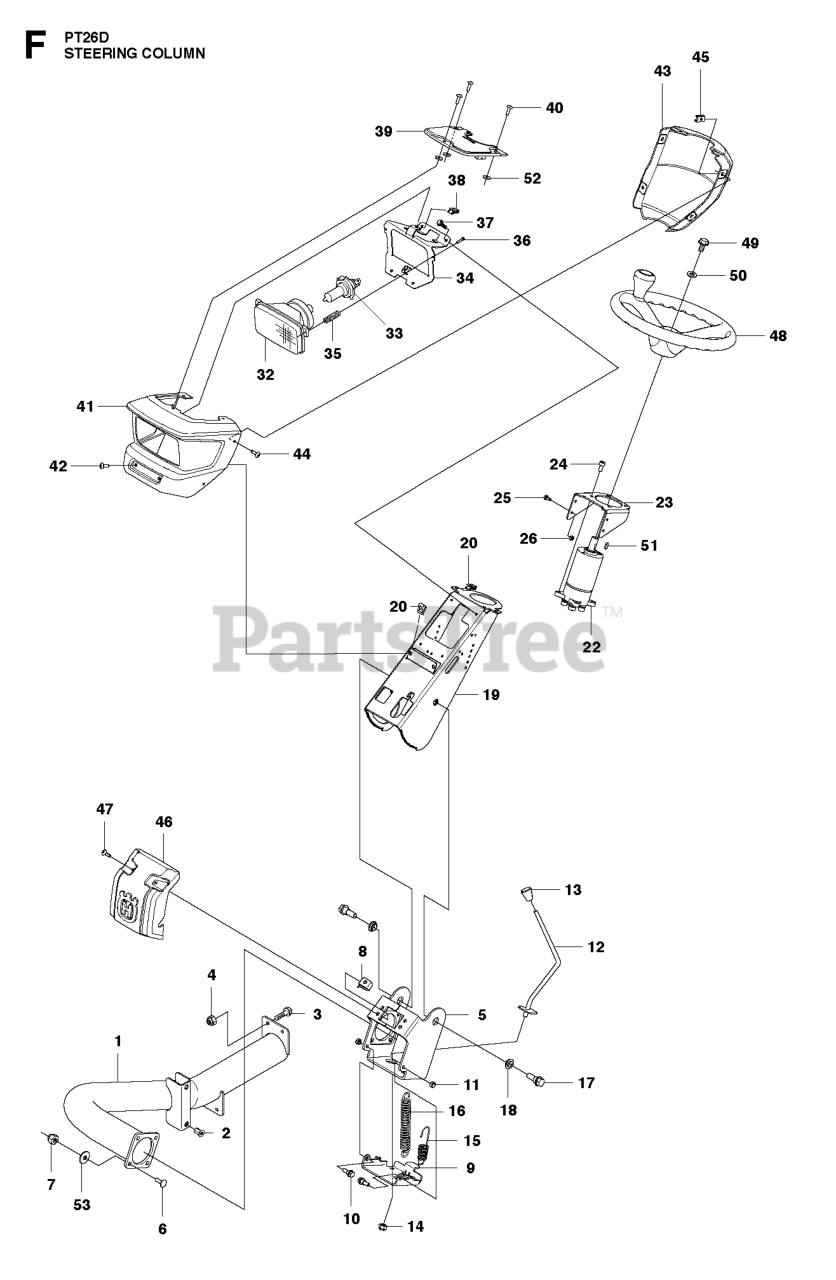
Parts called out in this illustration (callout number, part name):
4	LOCKNUT M8
7	LOCKNUT M8
11	LOCKNUT M8
16	DRAW SPRING L=108
25	BOLT FLANGE - M6X20
26	LOCKNUT M6
49	SCREW EHHFM
53	WASHER BRB 8.4X17
